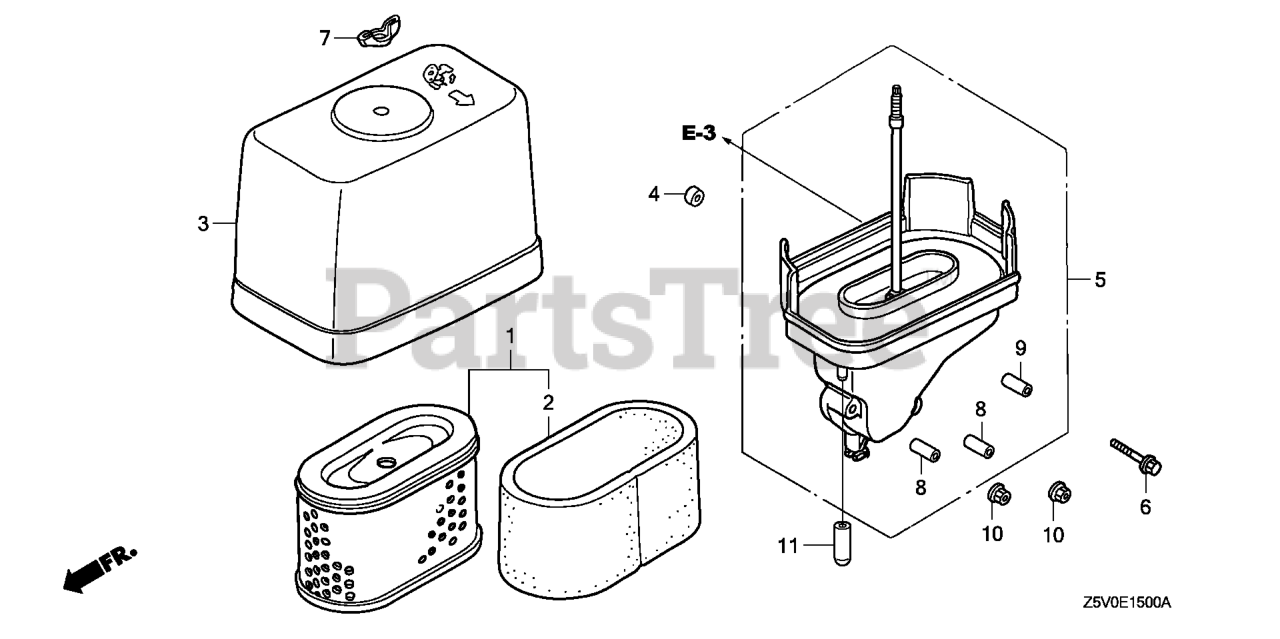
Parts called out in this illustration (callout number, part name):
1	ELEMENT, AIR CLEANER
3	COVER, AIR CLEANER
5	ELBOW, AIR CLEANER
6	BOLT, FLANGE (6X35)
7	WINGNUT, TOOL BOX SETTING
8	COLLAR, AIR CLEANER
9	COLLAR, AIR CLEANER
10	NUT, FLANGE (6MM)
11	CAP, SEALING
